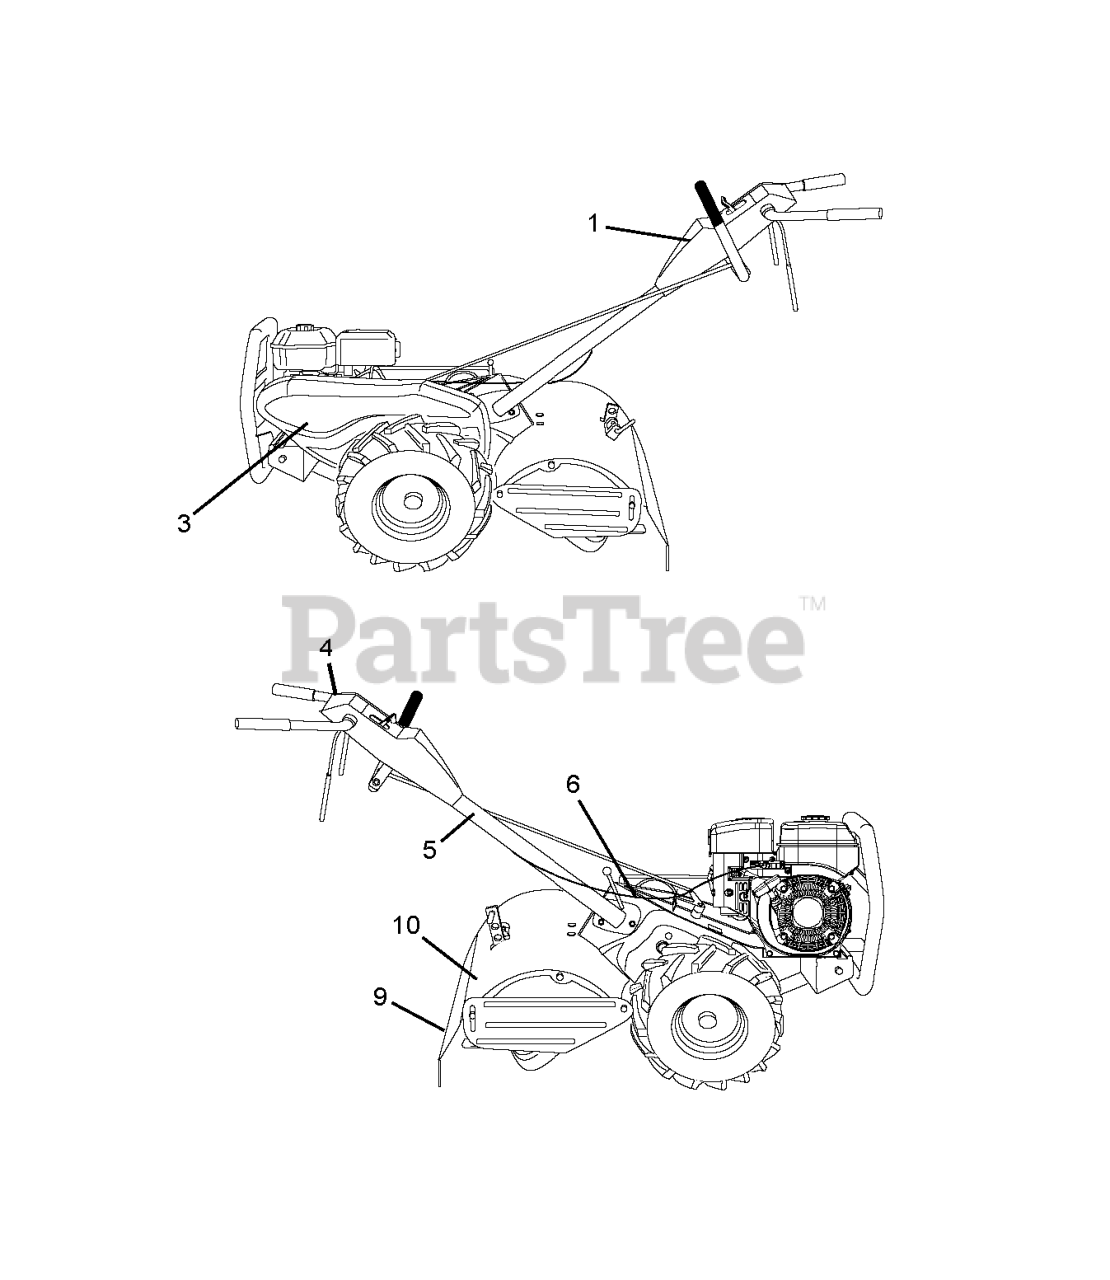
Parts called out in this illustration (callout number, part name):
3	RP.DECAL.BADGE.170MM.TEXTLOGO
4	DECAL, CONTROL TINE
5	DECAL.PLACEMENT.HAND.SYMBOLS
6	DECAL.SHIFT.INDICATOR.TILLER
9	DECAL.WARNING.4-SYM.TILLER.INT
10	DECAL EUROPE STANDARD CE
